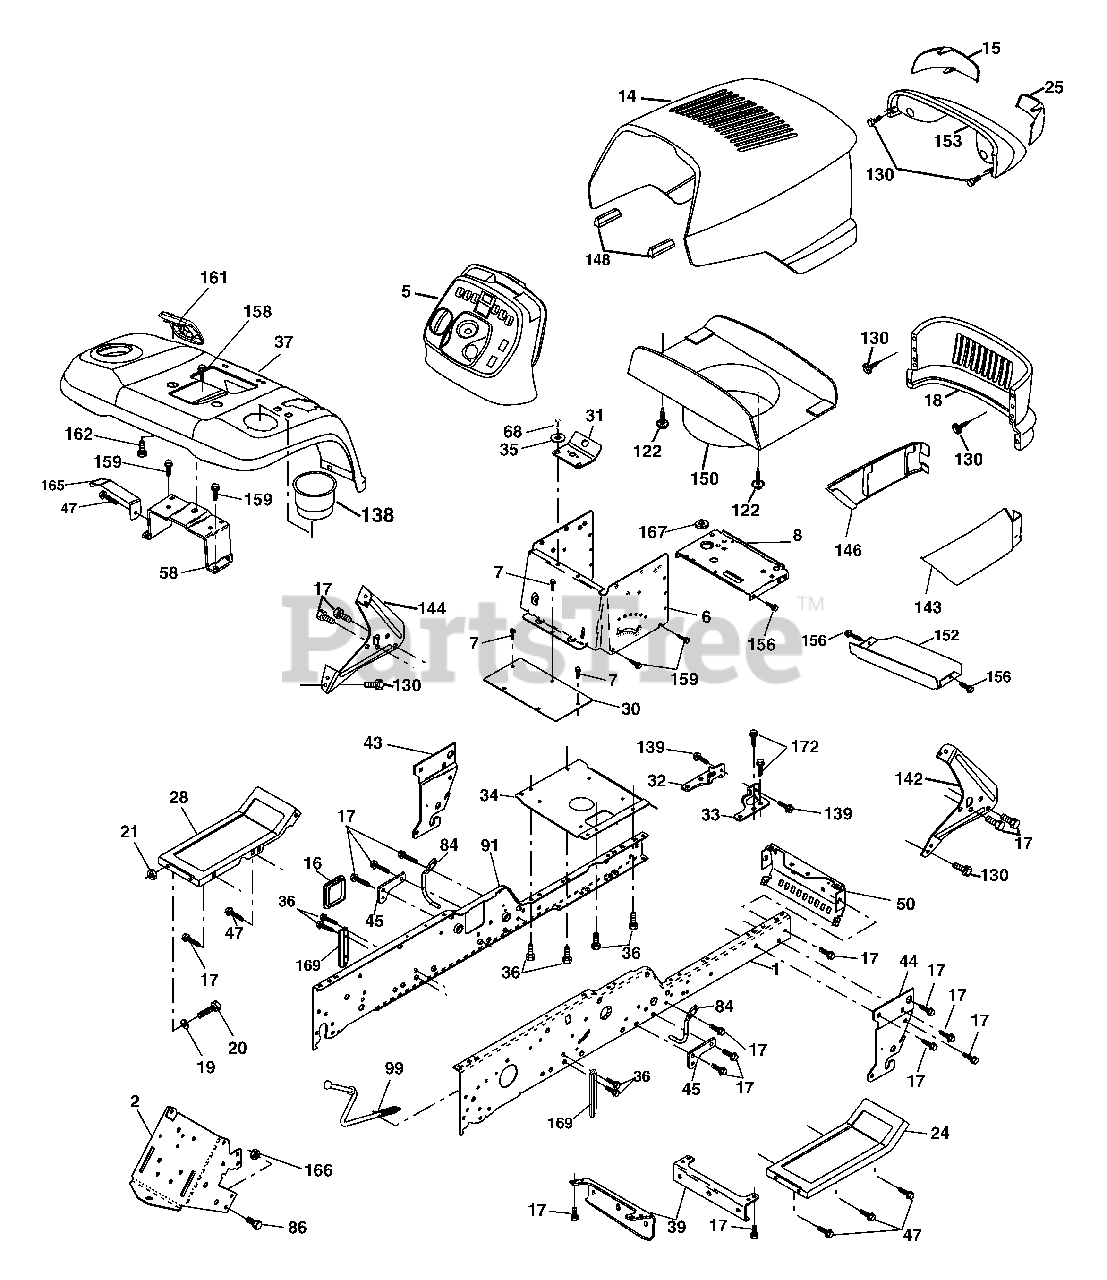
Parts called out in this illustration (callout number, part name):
1	Rail, Kit RH
2	Drawbar, Gt
5	Dash, Plastic
6	Dash, 1PCS, Lower
7	Screw, Thd Cut 1/4-20 x 1/2
8	Support, Battery
14	Hood Asm., Pnt
15	Lens LH
16	Cover, Access
17	Screw, 3/8-16 x 3/4
19	Washer 13/32 x 13/16 x 12 Ga.
20	Bolt, Fin Hex 3/8-16 x 1 Gr.5
21	Nut Lock Hex w/Ins 3/8-16 unc
24	Footrest, RH
25	Lens RH
28	Footrest, LH
31	Bracket Supt 1-pc Vgt Steering
32	Bracket, Frame Pivot Lh
33	Bracket, Frame Pivot Rh
34	Plate Asm Engine Chassis
35	Washer 11/32 x 11/16 x 16 Ga.
36	Screw 5/16-18 x 3/4
37	Fender, Pnt.
39	Bracket, Axle Front
43	Bracket, Spnsn Front Lh
44	Bracket, Spnsn Front Rh
45	Bracket Asm., Susp Chassis
47	Screw Thdrol 3/8-16 x 1/2
50	Bracket, Chassis Front
58	Bracket Asm., Fender
68	Screw, 5/16-18 x 1/2
86	Bolt Hex 7/16-14 x 1 1/4 Gr. 5
91	Rail, Kit Lh
99	Rod Asm. Bypass
122	Screw Hex WSHD 8-18 x 7/8
130	Screw Hw Hd Hi-Lo #13-16 x 3/4
138	Cupholder
139	Bolt Shoulder 5/16-18
142	Bracket Dash Stealth RH
143	Skirt Grille RH
144	Bracket Dash Stealth LH
146	Skirt Grille LH
148	Extrusion Bumper
150	Duct Heat Hood
152	Shield, Browning
153	Light Box Asm w/Lens
156	Screw 5/16-18 x 3/4
158	Screw 3/8-16 x 1/2
159	Screw Hexwsh THDR 3/8-16 x 3/4
161	Consol Fuel Window
162	Screw Hex Wsh Hi-Lo 1/4-1/2 unc
165	Bracket Support Tank
166	Nut, Lock Hex 7/16 unc
167	Bushing Snap
169	Bracket Chassis Sway
170	Bolt Shoulder
172	Screw 3/8 x 16 x .875
